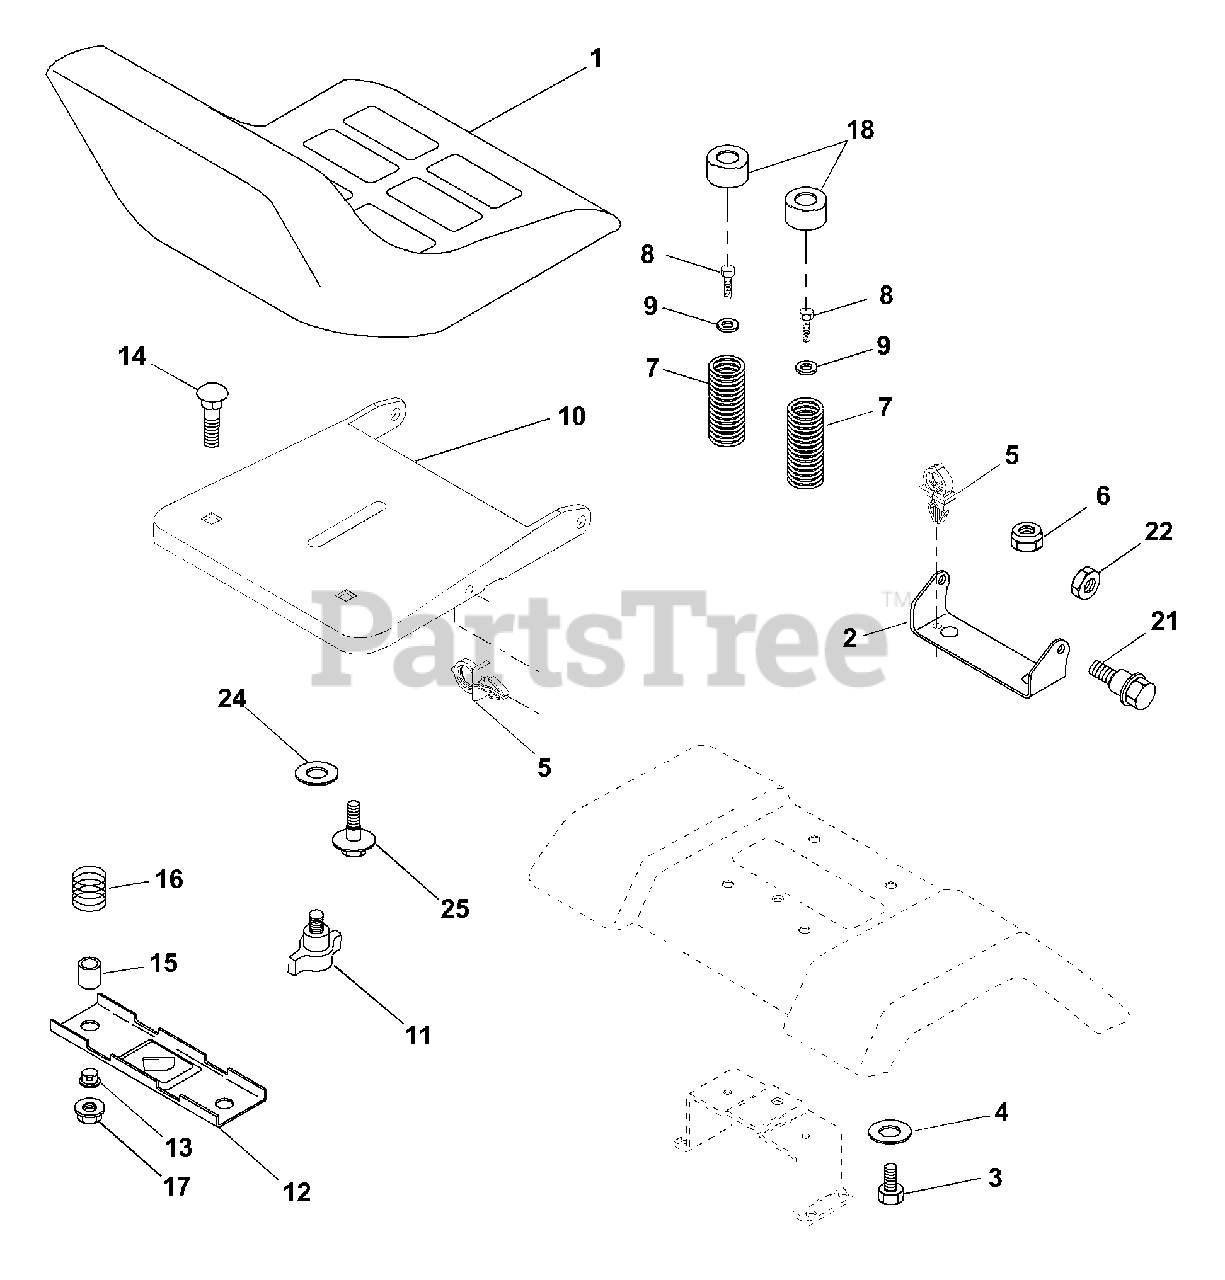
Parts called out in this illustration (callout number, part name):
1	Seat
2	Bracket Pivot Seat 8 720
3	Bolt Fin Hex 3/8-16unc X 1
4	Washer 13/32 X 1 X 10 Ga
5	Clip Push-In
6	Nut Hex w/Ins. 3/8-16 Unc
7	Spring Seat Cprsn 2 250 Blk Zi
8	Screw Thdrol 3/8-16 X 1-1/2
9	Washer 13/32 X 1 X 14 Ga.
10	Pan Seat
11	Knob Seat Adj Wingnut
12	Bracket Mounting Switch
13	Bushing Snap Blk Nyl 50 Id
14	Bolt Rdhd Sqnk 1/4-20x1-1/2
15	Spacer Split 28 x .88 Zinc
16	Spring Cprsn Plate
17	Nut Lock 1/4 Lge Flg Gr 5 Zinc
18	Cap Spring Seat
21	Bolt Shoulder 5/16-18 Unc
22	Nut Hex Lock W/Ins 5/16-18
24	Washer 17/32 X 1 X 12 Ga.
25	Bolt Shoulder 5/16-18 X 62
